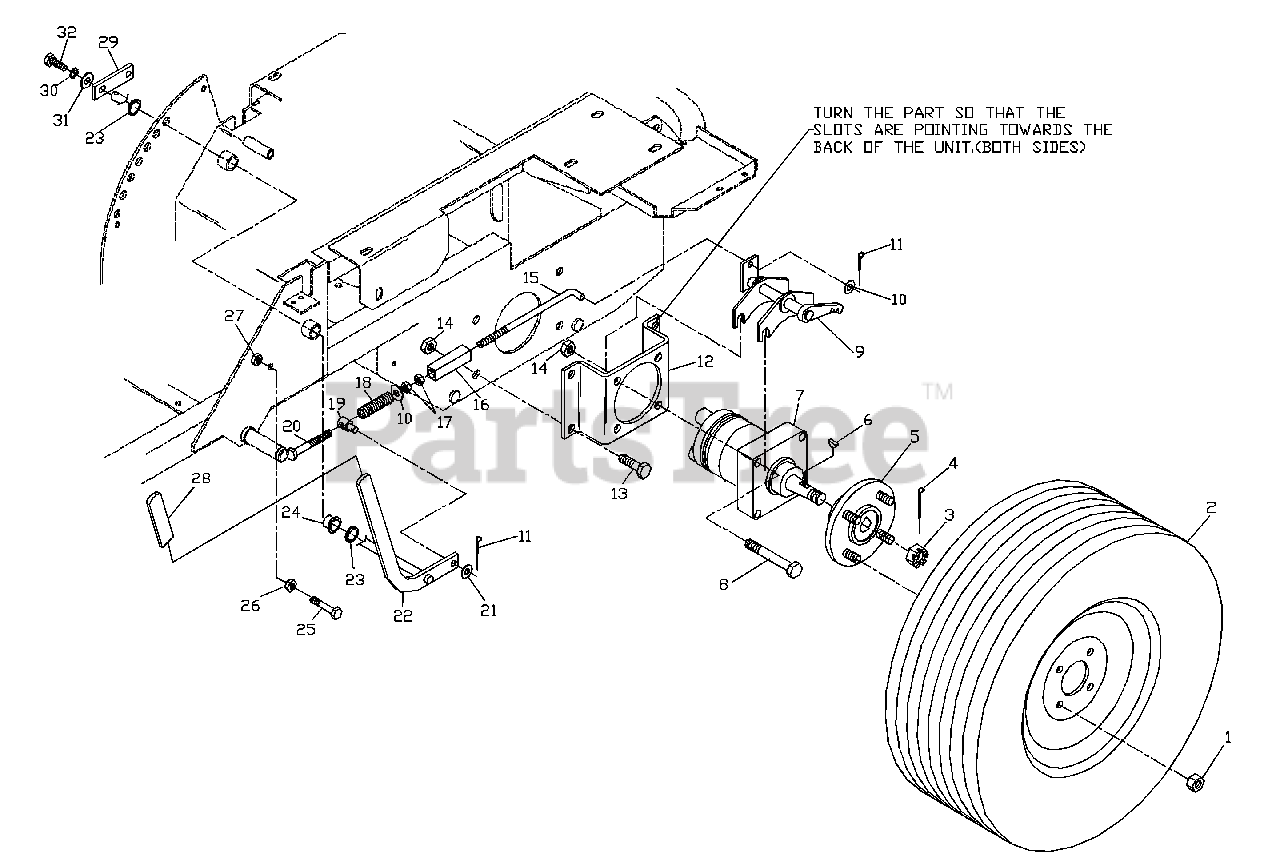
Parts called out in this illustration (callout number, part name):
1	LUG NUT 1/2F
2	REAR TIRE ASM.(COMPLETE)
2	RIM
2	VALVE STEM
3	HEX SLOTTED NUT
4	COTTER PIN
5	HUB, W/SPROCKET
6	KEY, #808 WOODRUFF
7	WHEEL MOTOR
8	HCS 1/2C X 2 3/4
9	BRAKE WELDMENT LEFT
10	WASHER 5/16 FLAT
11	1/8 X 3/4 COTTER PIN
12	MOTOR STANDOFF
13	HCS 1/2C X 1 1/4 SERRATED HEAD
14	NUT 1/2C NYLOC
15	BRAKE LINKAGE
16	TURNBUCKLE
17	5/16C HEX NUT
19	BRAKE SWIVEL
20	HCS 5/16C, SPECIAL
21	WASHER 3/8 FLAT
22	PIVOT SHAFT
23	1/2" MACHINERY BUSHING
25	HCS 3/8C X 1 3/4
26	3/8C WHIZ NUT
27	NUT 3/8C CENTERLOCK
29	ARM, PARK BRAKE
30	1/4" LOCKWASHER
31	WASHER 1/4" FLAT
32	HCS 1/4C X 5/8"
